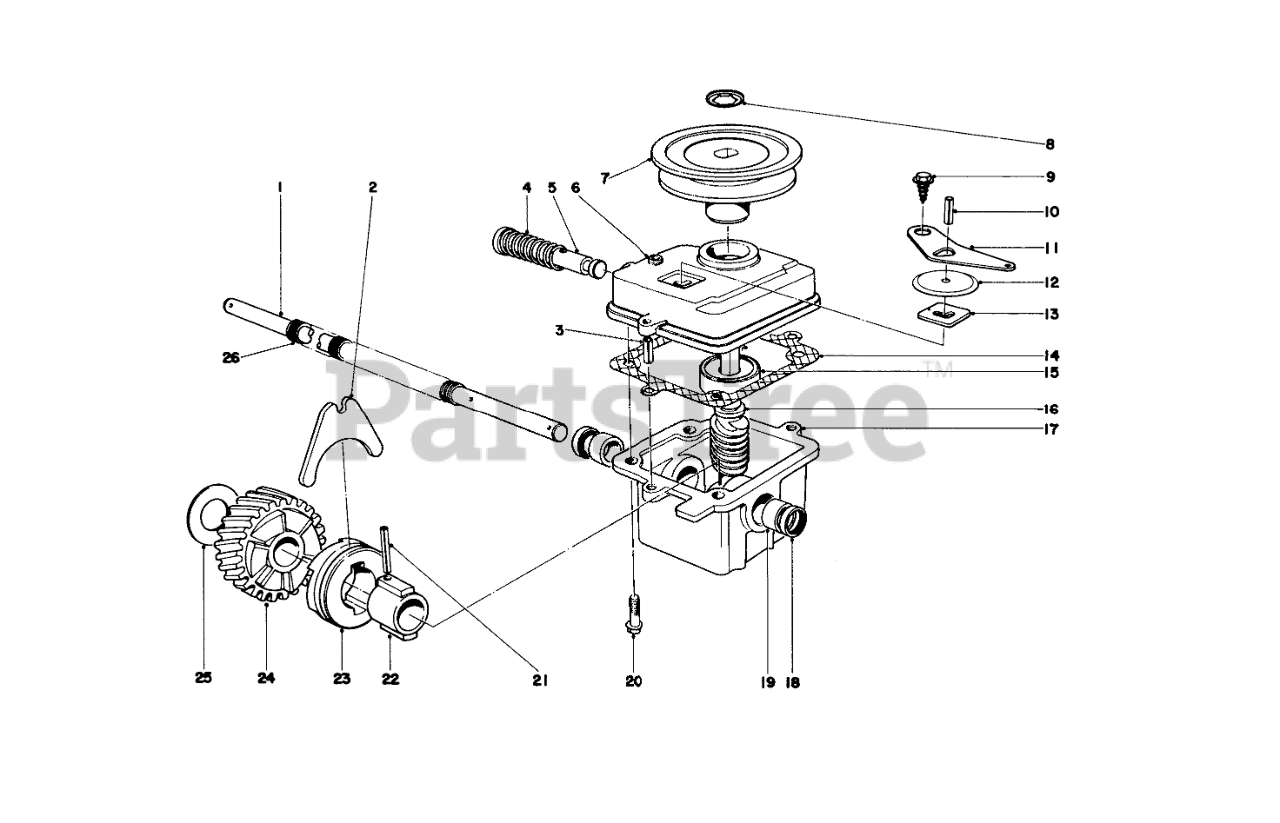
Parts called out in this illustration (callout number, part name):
1	Drive Shaft
2	SHIFTER FORK
3	3/16 X 1/2 ROLL PIN
4	SPRING
5	Shift Rod
6	GEAR CASE COVER
7	PULLEY
8	PUSH-ON 93-3236
9	Screw
10	PIN-ROLL
11	SHIFTER ARM
12	TRANS DUST COVER
13	LATCH PLATE
14	GASKET
15	Bearing
16	WORM SHAFT
17	Gear Case (Incl. Ref. #18 & 19)
18	Seal
19	Bushing
20	Screw
21	COIL PIN
22	SLEEVE
23	CLUTCH JAW
25	THRUST WASHER
26	DRIVE SHAFT COVER
